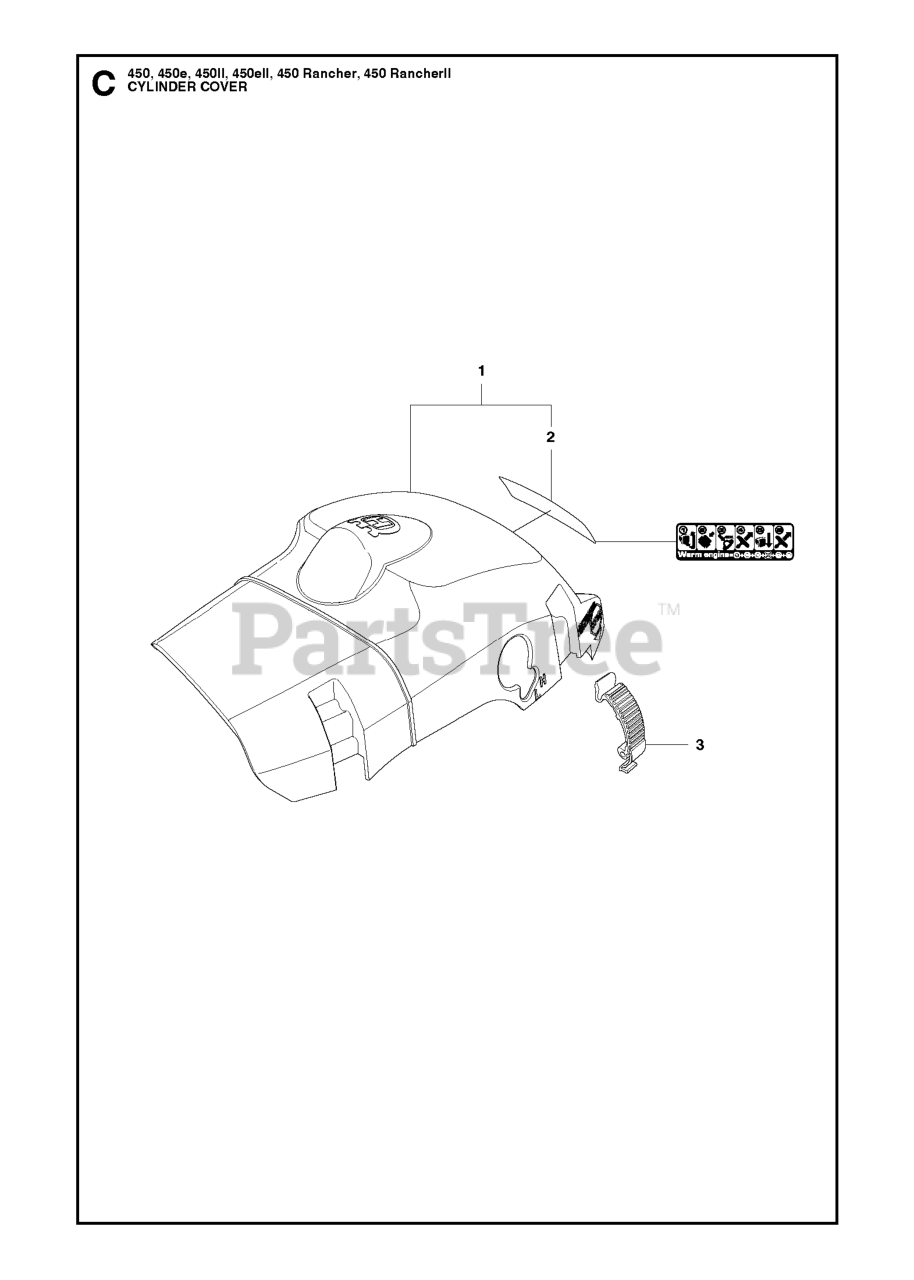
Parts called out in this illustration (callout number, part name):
1	CYLINDER COVER ASSY
1	CYLINDER COVER SYSTEM
2	LABEL START REMINDER
2	LABEL
3	BUCKLE ORANGE
